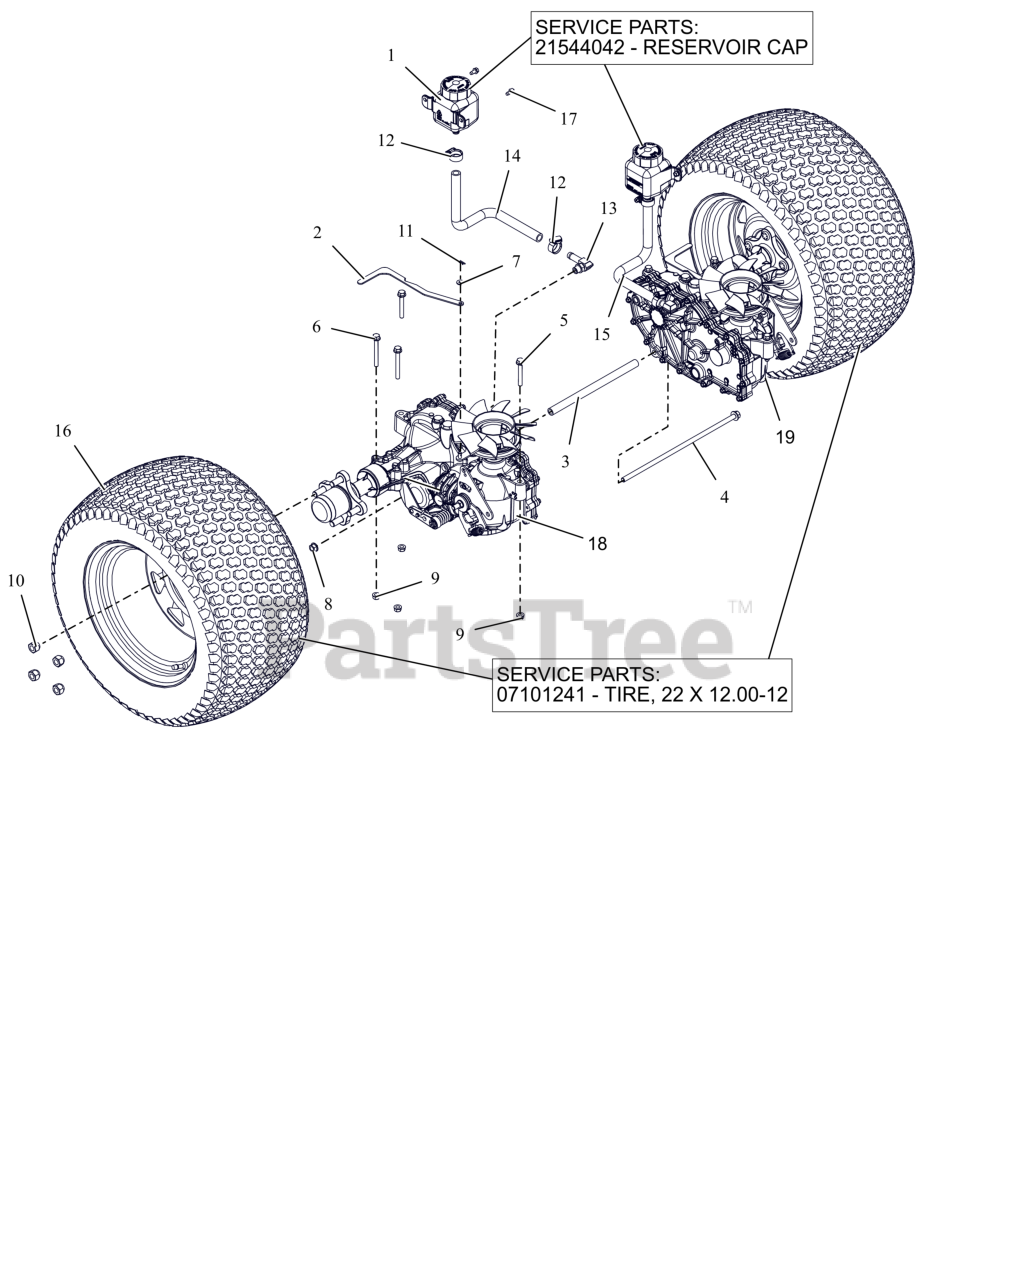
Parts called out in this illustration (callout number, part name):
1	TANK, EXPANSION
2	BRKT, VALVE DUM
3	SPCR, TRANSAXLE .406 ID X .630 OD X 9.95LG (BLACK)
4	BLT, HEX-FLG 0.375-16X13 GR5 ZC120
5	BLT,HEX-FLG .31-18X2.25 G5 ZCC
6	BLT,HEX-FLG .31-18X2.75 G5 ZCC
7	WSHR,FLT .281X.625X.065 ZCC
8	NUT-LK-TOP-FLG .38-16 ZC120
9	NUT,LK-CTR-FLG .31-18 GF ZCC
10	NUT, WHEEL .50-20 ZCC
11	PIN, HAIR #225 .072X1.09
12	CLAMP,.88 DIA. HOSE
13	FITTING, HYD (90 DEG)
14	HOSE, FORMED EXPANSION -HD RH
15	HOSE, FORMED EXPANSION -HD LH
16	ASM, WHL/TIRE 22X12.00-12 K500
17	SCR-TAP .25-20X.50 HWH ZCC
18	TRANSAXLE, ZT3200 - RH
19	TRANSAXLE, ZT3200 - LH
